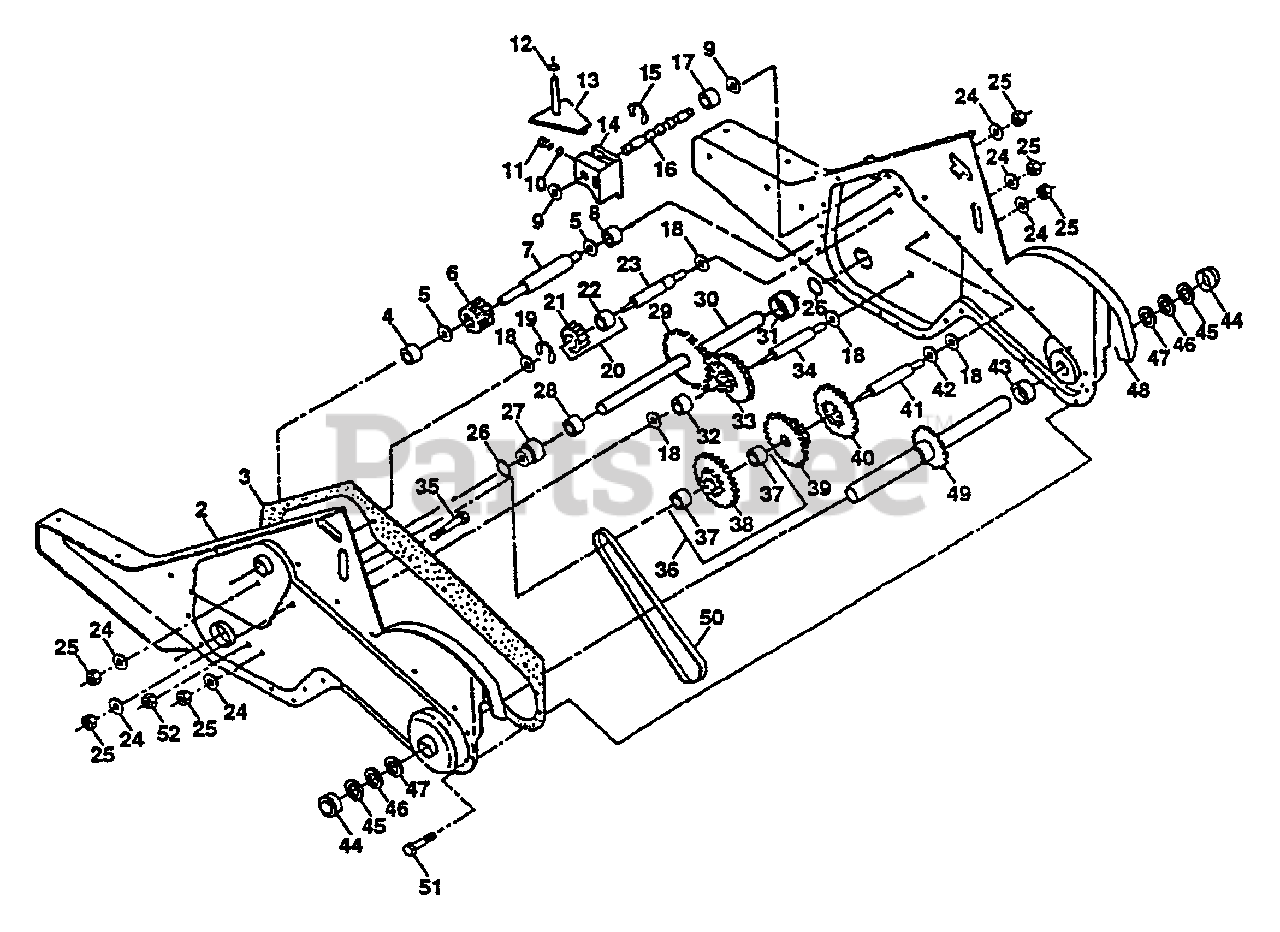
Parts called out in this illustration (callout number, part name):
1	Transmission Assembly
2	Gearcase, L.H. w/Bearing
3	Gasket, Gearcase
4	Bearing, Needle
5	Washer, Thrust 5/8 x 1.10 x 1/32
6	Pinion, Input
7	Shaft, Input
8	Bearing, Needle
9	Washer, Seal
10	Ball, Steel
11	Spring, Shift, Fork
13	Arm, Shift
14	Fork, Shift
15	Ring, Klip
16	Shaft, Shift
17	Spacer, Split
19	Ring, Klip
20	Gear, Assembly, Reverse Idler
21	Gear, Reverse Idler
22	Bearing, Needle
23	Shaft, Reverse Idler
24	Washer, Lock 7/16
25	Nut, Hex 7/16-20
27	Bearing, Shaft, Ground Drive
28	Spacer 0.765 x 1.125 x 1.23
29	Chain #35-50 Pitch
30	Ground Shaft Assembly
31	Bearing, Shaft, Ground Drive
32	Spacer 0.70 x 1.00 x 1.150
33	Sprocket and Gear Assembly
34	Shaft, Reduction (2nd)
35	Screw, Whiz, Lock 5/16-18 x 3-1/2
36	Sprocket Assembly w/Bearing
37	Bearing, Needle
38	Sprocket, Tine
39	Gear, Cluster, Red 1st & 2nd
40	Gear, Reverse
41	Shaft, Reduction (1st)
42	Washer, Thrust
43	Spacer 1.01 x 1.75 x 0.760
44	Cup, Formed
45	Ring, Spiral
46	Seal, Ring, Rubber
47	Seal, Oil
48	Gearcase, R.H. w/Bearing
49	Shaft, Tine
50	Chain, Roller #50-50 Pitch
51	Screw 1/4-20 x 1/2
52	Nut, Hex 5/16-18.
